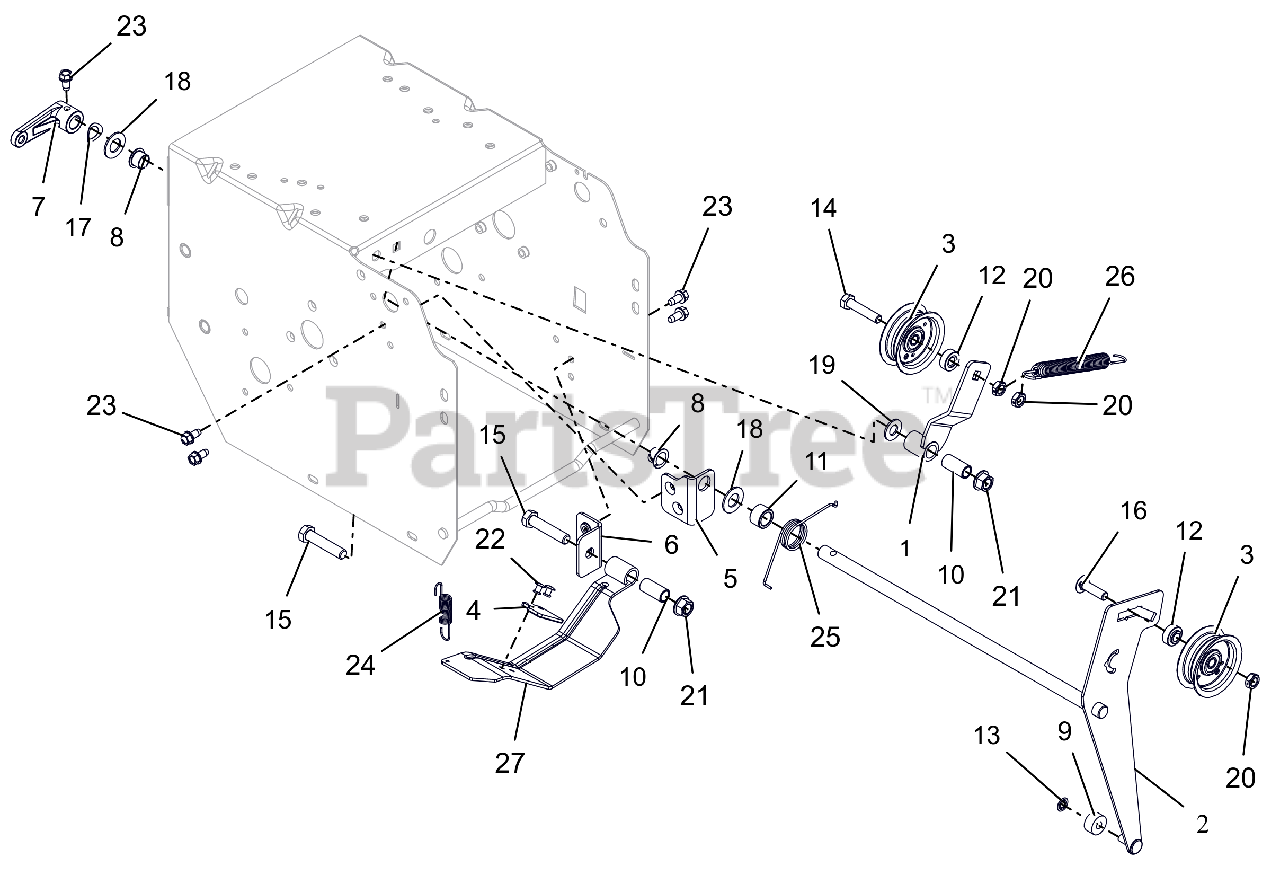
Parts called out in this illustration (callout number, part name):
1	ARM, TRACTION IDLER
2	WELDMENT, ATTACHMENT IDLER ARM
3	IDLER, FLAT - 2.00"
4	PAD, BRAKE
5	BRACKET, MOUNT - IDLER ARM
6	BRACKET, MOUNT - BRAKE
7	ARM, CLUTCH - ATTACHMENT
8	BUSHING, POLYLINER-.50 SPLIT
9	BSHG,SLV .265 X .625 X .375
10	BSHG-SLV .385X.500X1.045
11	BSHG-SLV .510X.751X.475
12	SPCR, BRG .315X.500X.358X.281
13	RG-RTNG-EXT .250X.010
14	@BLT-HEX .31-18X1.50 GR5 YWZC
15	@BLT-HEX .38-16X1.75 GR5 YWZC
16	BLT-RDHDSQSHNK.31-18X1.13 G5YZ
17	WSHR-WAVE .50X.75X.015 .13FRHT
18	WSHR-FL-STL.531X1.00X.063 YWZC
19	@WSHR-FL-STL.406X.812X.065 YWZ
20	@NUT-LK-CTR-JAM .31-18 YWZC
21	@NUT-LK-TOP-FLG .38-16 YWZC
22	RVT-POP .187 YZ
23	SCR-TAP .25-20X.50 HWH TR YWZ
24	SPRING-EXT .437 X .438 X 2.64
25	SG-TORS .075 X .955
26	SPRING, SWIVEL HOOK EXTENSION
27	BRAKE ARM W/PAD
